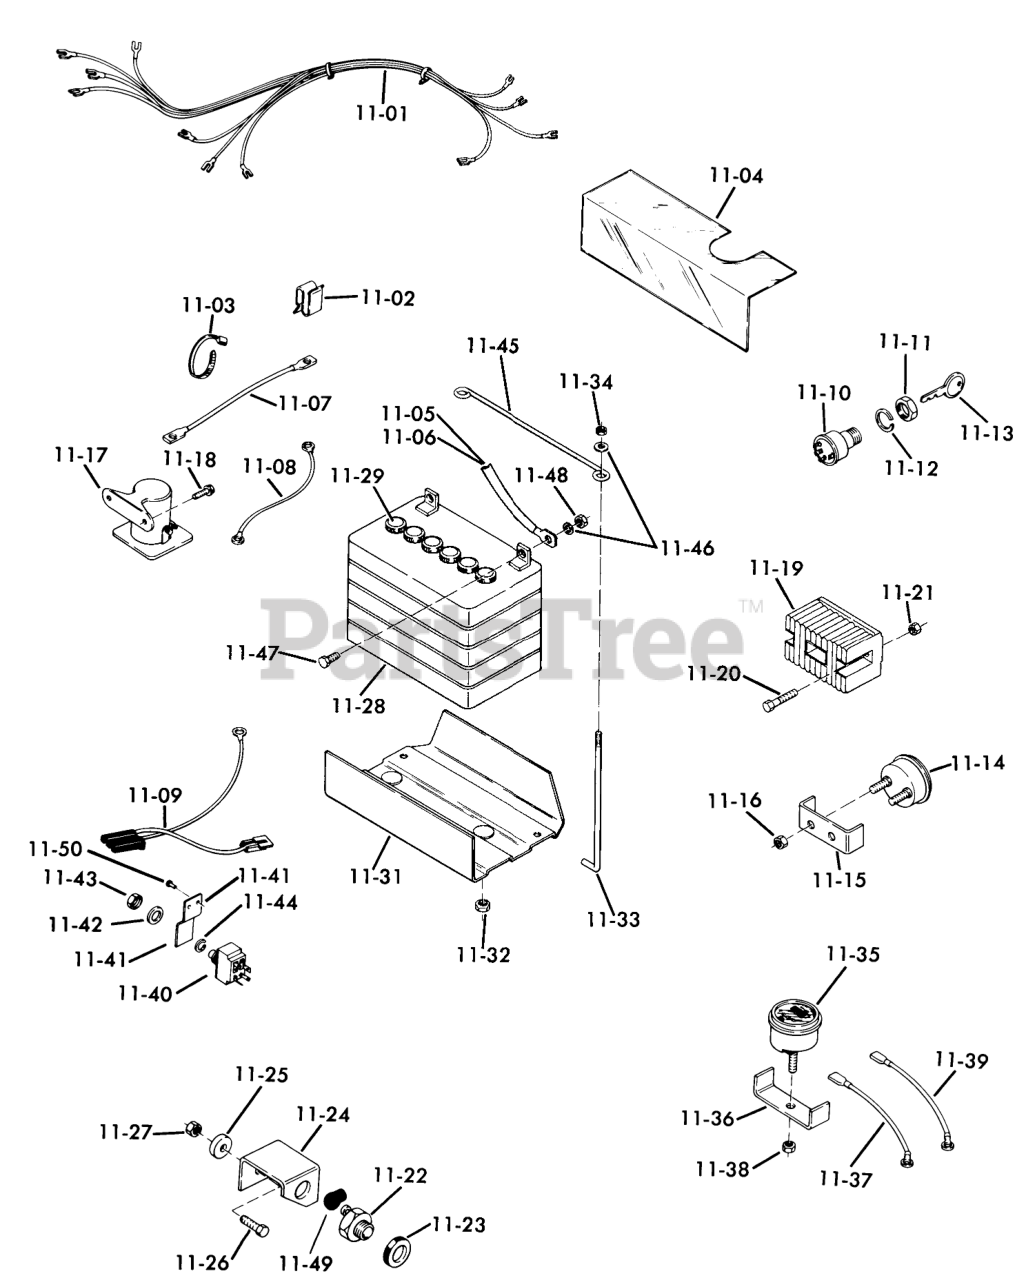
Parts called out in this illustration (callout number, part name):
11-01	WIRING HARNESS & DIA
11-02	SPEED CLIP
11-03	PLASTIC TIE
11-04	CONTROL PROTECTOR
11-05	Wire
11-06	Wire
11-07	Wire
11-09	Wire Assembly-Interlock to Harness
11-10	SWITCH-IGNITION
11-12	LOCKWASHER
11-13	Key-EL
11-14	AMMETER W/CLAMP
11-15	Clamp
11-16	HEX NUT 10-32 E.S.
11-17	Solenoid
11-18	Screw
11-19	REGULATOR-RECTIFIER
11-20	Bolt
11-21	Nut
11-22	SWITCH-INTERLOK CLUT
11-23	NUT-SPECIAL 9/16-18
11-24	Bracket
11-25	WASHER
11-26	BOLT
11-27	Nut
11-28	Battery
11-31	Battery
11-32	Nut
11-33	Hook
11-34	Nut
11-35	Hour Meter
11-36	Clamp
11-37	SY WIRE HR METER G
11-38	Nut
11-39	Wire Assy
11-40	SWITCH-CLUTCH
11-41	CLIP-SWITCH
11-42	WASHER
11-43	NUT-HEX
11-44	TAB-WASHER
11-45	ROD-HOLD DOWN
11-47	Bolt
11-48	Nut
11-49	Terminal Cover
11-50	RIVET
